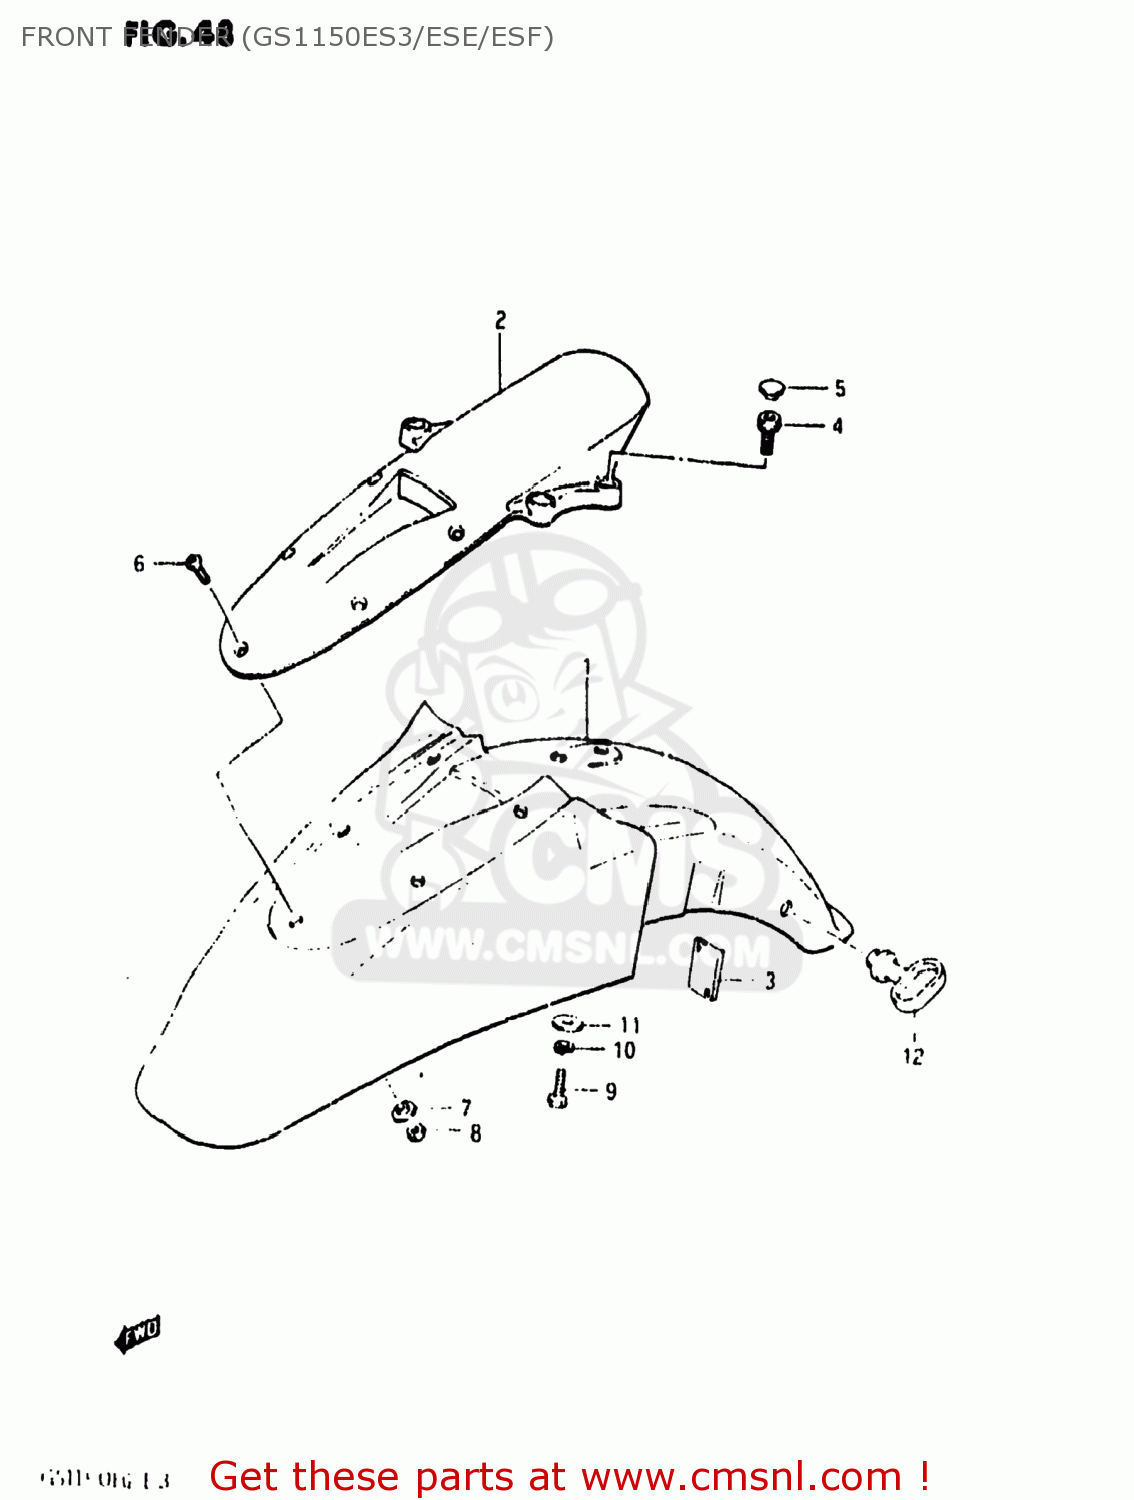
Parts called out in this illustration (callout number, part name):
1	FENDER,FRONT
2	BRACE,FR FENDER CTR
3	CUSHION
4	BOLT
5	CAP(OD:14.5)
6	SCREW, CENTER
7	WASHER
8	NUT 8MM
9	BOLT, UPPER
10	LOCK WASHER
11	WASHER
12	GUIDE,CABLE
